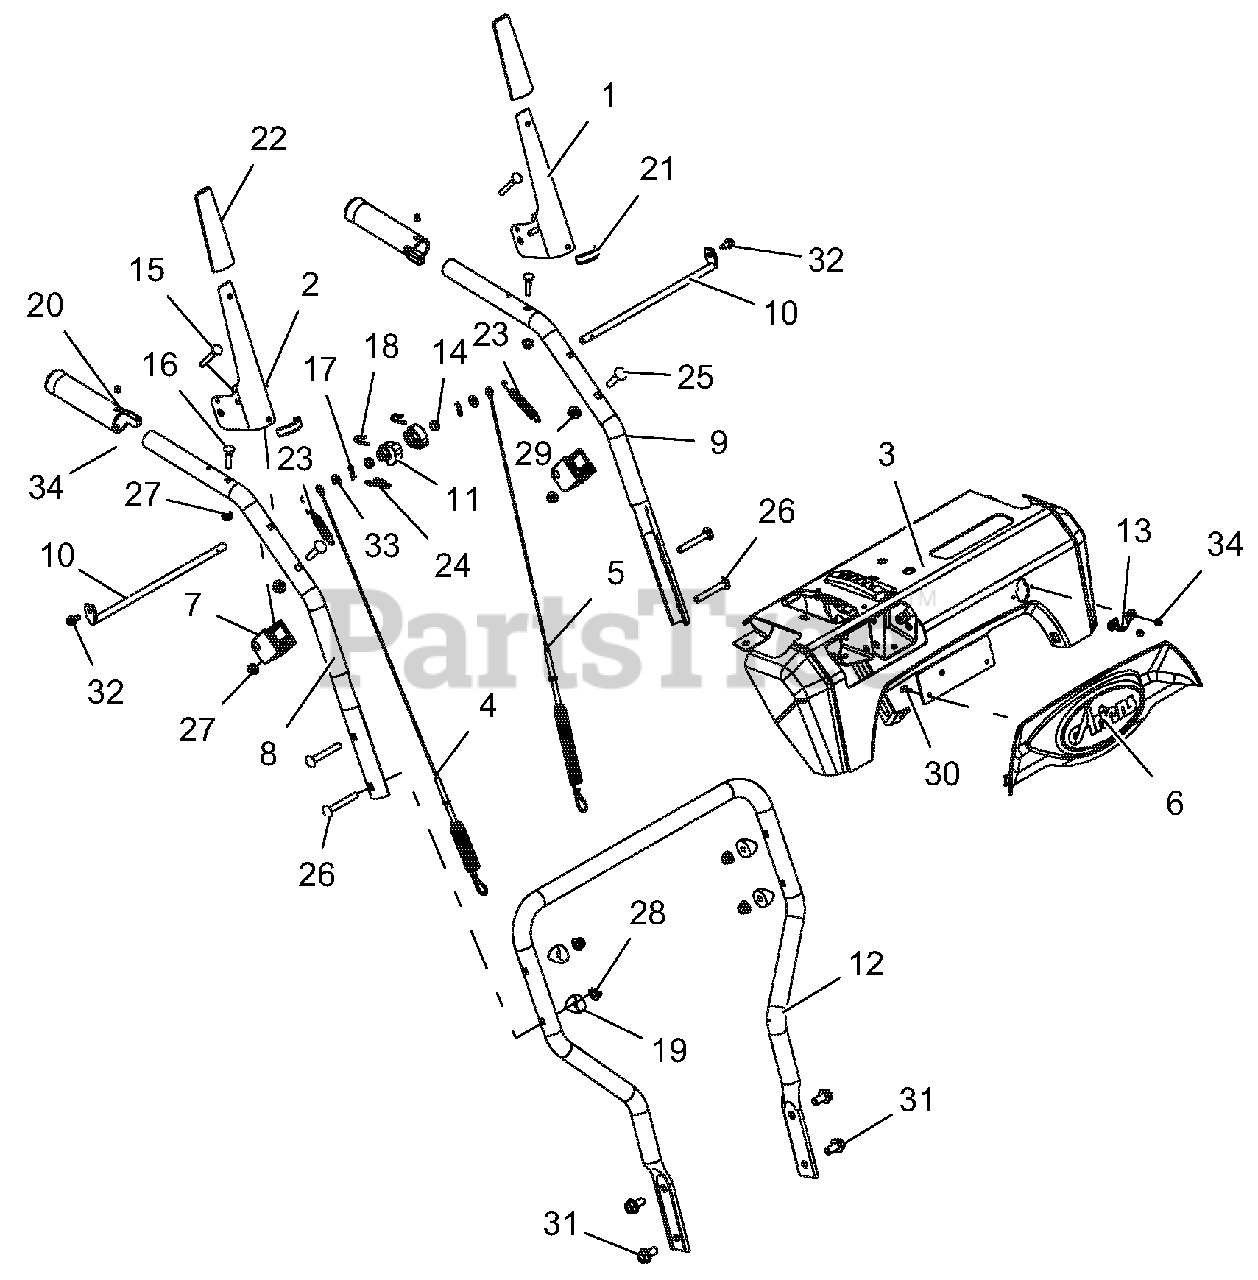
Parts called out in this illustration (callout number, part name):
1	LEVER, CLUTCH-LH
2	LEVER, CLUTCH-RH
3	CONTROL PANEL W/DECAL QT2
4	CABLE, AUGER (DELUXE & PRO)
5	CABLE, UPPER TRACTION
6	DASH BEZEL, ARIENS LOGO - PRO
7	BLOCK, CLUTCH PADDLE
8	HANDLEBAR, UPPER - RH
9	HANDLEBAR, UPPER - LH
10	ROD, PADDLE MOUNT - PRO
11	CAM, INTERLOCK
12	HANDLEBAR, LOWER - DELUXE
13	GROMMET, CABLE, QUICK TURN 2
14	BUSHING, POLYLINER-.38 SNAPIN
15	BLT-RDHDXLSQNK .25-20X2.0 G5YZ
16	BLT-RDHDXLSQNK.25-20X1.25 G5ZC
17	PIN-HAIR INT .06X.18X.77
18	PIN, SPRING CLIP
19	SPACER, HANDLEBAR
20	HEATED GRIP, MAGURA
21	EDGING, CLUTCH PADDLE - 2.00"
22	CLUTCH PADDLE SLEEVE - GRAY
23	SPRING, EXTENSION
24	SPRING-EXT .047X.438X1.45
25	@BLT-RDHDSQNK .31-18X1.50 G5YZ
26	@BLT-RDHDSQNK .31-18X2.25 G5YZ
27	@NUT-LK-CTR-FLG .25-20 YWZC
28	@NUT-LK-NYL-FLG .31-18 YWZC
29	@NUT-LK-TOP-FLG .31-18 YWZC
30	SCR-TAP #10X.50 BOSS INDHXHD
31	BLT-SERHFWH .38-16X.75 YWZC
32	SCR-TAP .25-20X.50 HWH TR YWZ
33	@WSHR-FL-STL.281X.62X.065 YWZC
34	RVT-POP #43 .125X.313 STL ZINC
